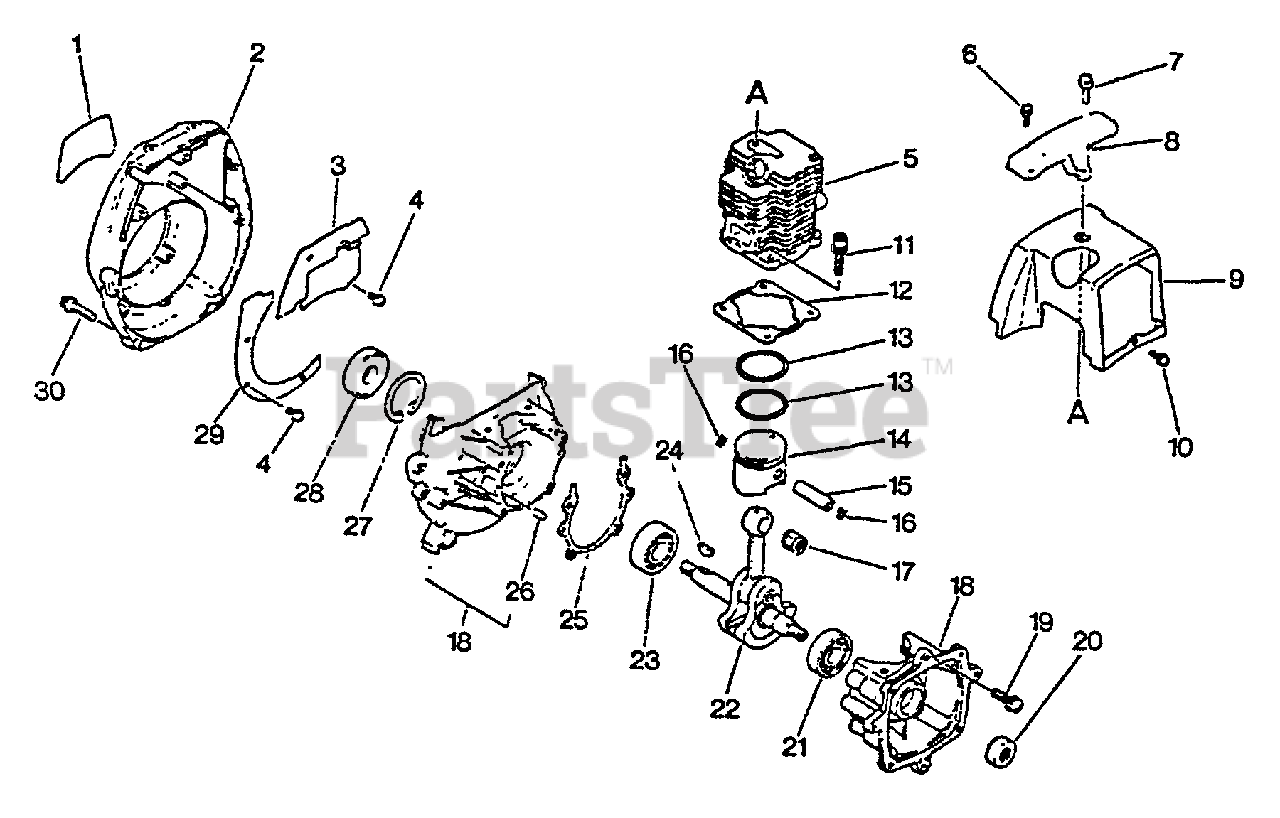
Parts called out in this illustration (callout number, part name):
1	LABEL, MODEL
2	COVER, FAN
3	PLATE, GUIDE
4	SCREW 4×8
5	CYLINDER
6	SCREW 4×14
7	SCREW 5×16
8	GUARD, TOP
9	COVER, ENGINE
10	SCREW 4×10
11	BOLT 5×20
12	GASKET, CYLINDER
13	RING, PISTON
14	PISTON
15	PIN, PISTON
16	RING, SNAP
17	BEARING, NEEDLE
18	CRANKCASE KIT
19	SCREW 5×25
20	SEAL, OIL 12
21	BEARING, BALL 6001
22	CRANKSHAFT ASSY
23	BEARING, BALL - 6201 C3
25	GASKET, CRANKCASE
26	PIN, LOCATING 4
27	RING, SNAP Ø32
28	SEAL, OIL 12
29	PLATE, GUIDE
30	SCREW 5×20
